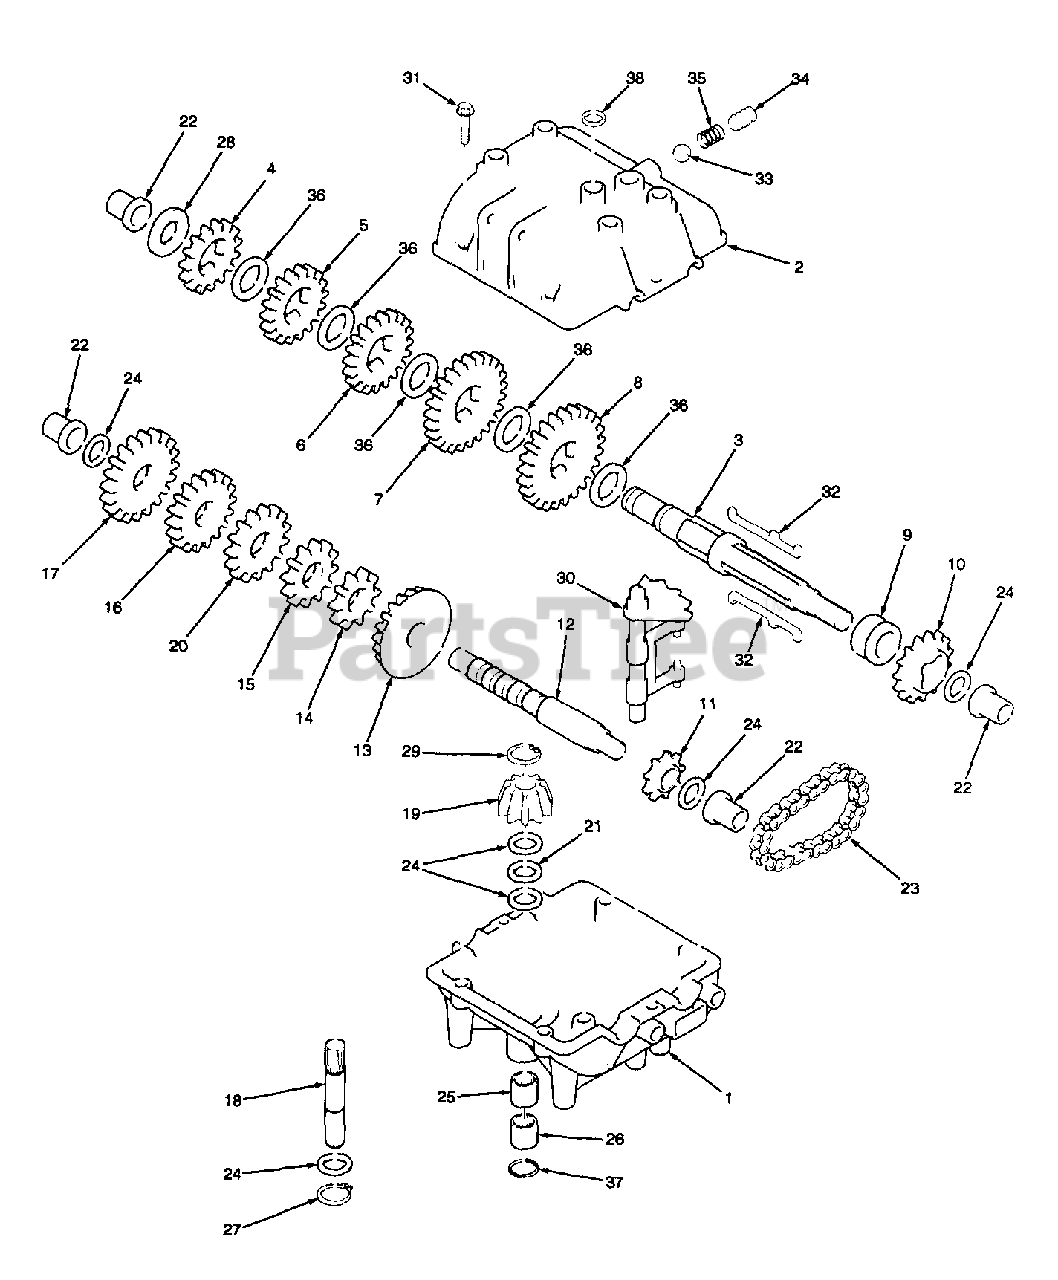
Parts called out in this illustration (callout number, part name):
1	Case, Transmission
2	Cover, Transmission
3	Shaft, Output & Brake
4	Gear, Spur (25 teeth)
5	Gear, Spur (30 teeth)
6	Gear, Spur (32 teeth)
7	Gear, Spur (35 teeth)
8	Gear, Spur (37 teeth)
9	Collar, Shift
10	Sprocket (18 teeth)
11	Sprocket (9 teeth)
12	Shaft, Counter
13	Gear, Bevel (42 teeth)
14	Gear, Spur (12 teeth)
15	Gear, Spur (15 teeth)
16	Gear, Spur (20 teeth)
17	Gear, Spur (25 teeth)
18	Shaft, Input
19	Bevel Pinion, Input
20	Gear, Spur (18 teeth)
21	Bearing, Thrust
22	Bushing, Flanged
23	Chain, Roller (No. 41 chain, 24 links)
24	Washer, Thrust
25	Bearing, Needle
26	Bearing, Needle
27	Ring, Retaining
28	Washer, Thrust
29	Ring, Retaining
30	Rod & Fork Assy, Shift
31	Screw, Flanged Hex Hd Thread, 1/4-20 x 1-1/4"
33	Ball, Steel, 5/16"
34	Screw, Set 3/8-16 x 3/8"
35	Spring
36	Washer, Thrust
37	"O" Ring
38	Seal, Square cut
